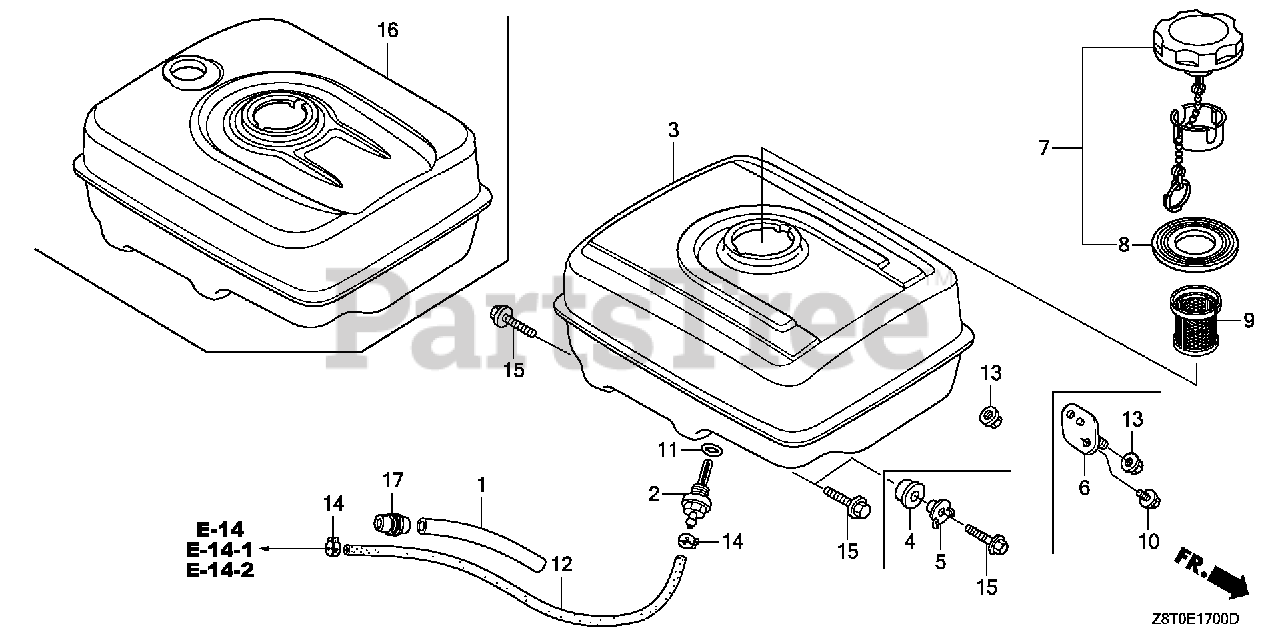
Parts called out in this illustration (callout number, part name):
1	RUBBER, SUPPORTER (107MM)
12	TUBE, FUEL (4.5X235) (FKM)
12	TUBE, FUEL (4.2X235) (FKM)
14	CLIP, TUBE (D8)
